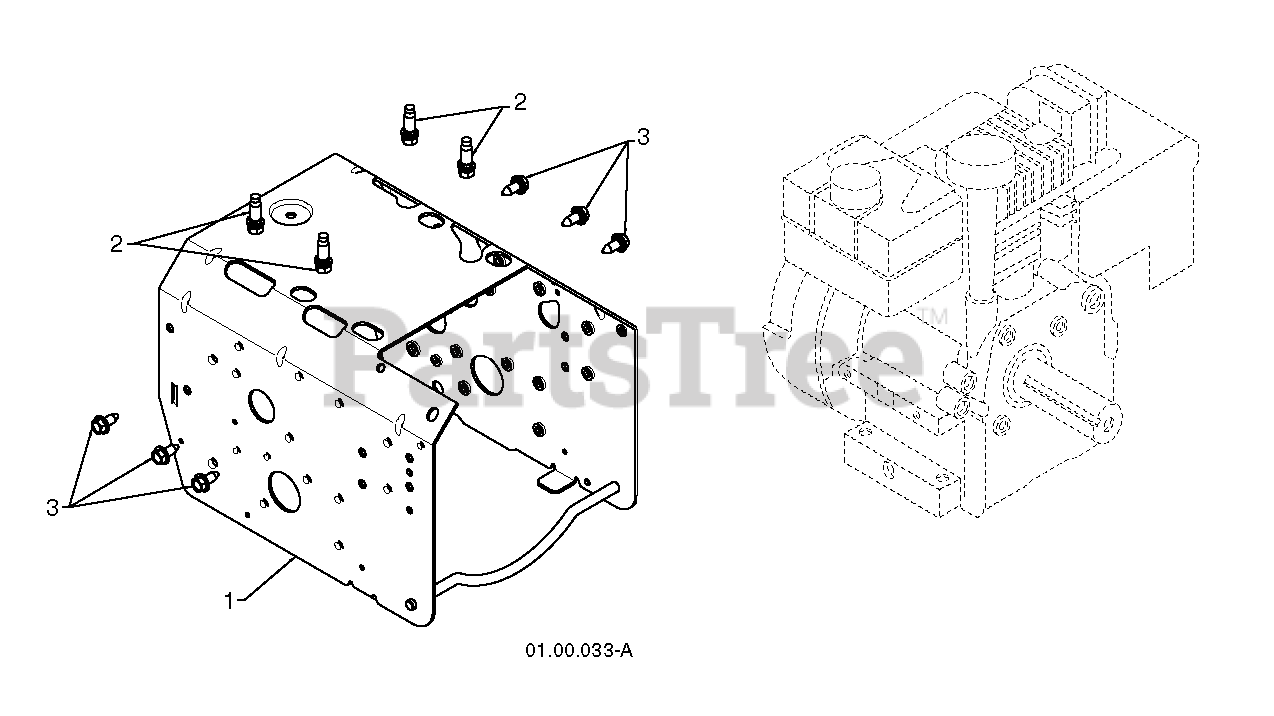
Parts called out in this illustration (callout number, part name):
1	FRAME.WELD.PNT.GEAR.ORANGE
2	BOLT 3/8-16X1-1/8
3	BOLT.HEX.HD.WASHER.5/16-18X.75
